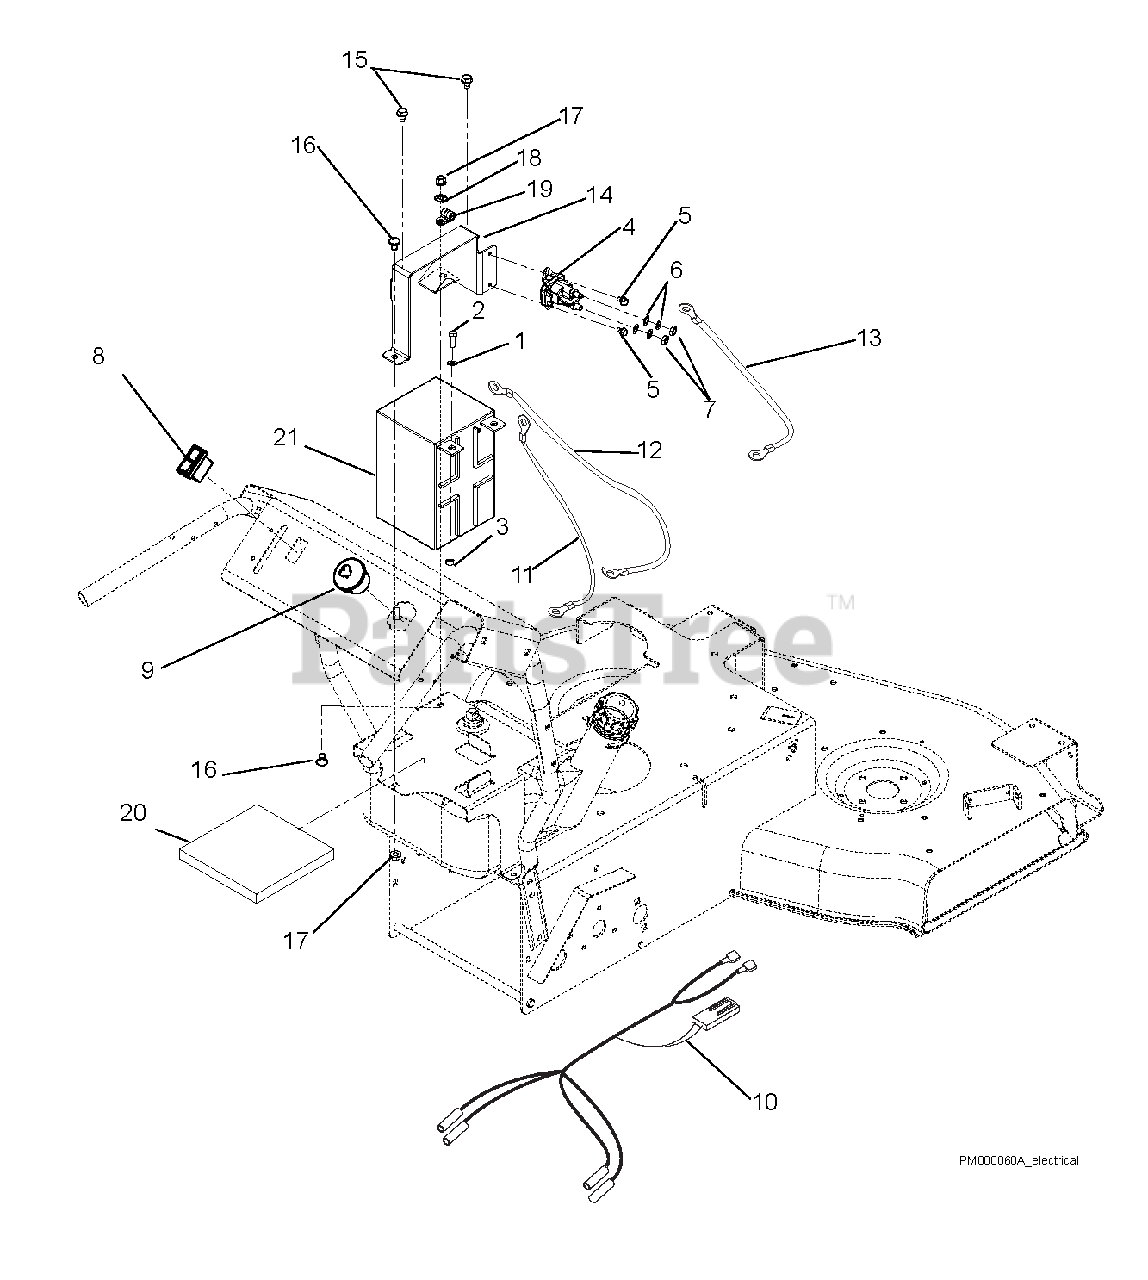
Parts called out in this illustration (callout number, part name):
1	@WSHR-FL-STL.281X.62X.065 YWZC
2	@BLT-HEX .25-20X.75 GR5 YWZC
3	NUT-KEPS .250-20
4	SOLENOID
5	@SCR-TAP .25-20X.37 HWH YWZ TR
6	WSHR-LOCK INT .31 YWZC
7	NUT-JAM .31-24 YWZC
8	SWITCH-ROCKER, MOMENTARY
9	KEYSWITCH-IGNITION 3 POS
9	BRKT, STRIPER MOUNT-RIGHT
10	HARNESS, WAW WIRING
11	ASSY, POS BATTERY 6.75"
12	CABLE, NEGATIVE 26" 6 GA.
13	CABLE, POS. BAT 18.50"
14	BRKT, BATTERY MOUNT
15	@SCR-TAP .31-18X.50 HWH TR YWZ
16	@BLT-RDHDSQNK .31-18X.50 G5YZ
17	@NUT-LK-TOP-FLG .31-18 YWZC
18	NUT-PUSH .312
19	CLAMP, CUSHIONED STEEL
20	BATTERY MAT WAW 2012
21	BATTERY, 12V 20HR;190CCA GEP
